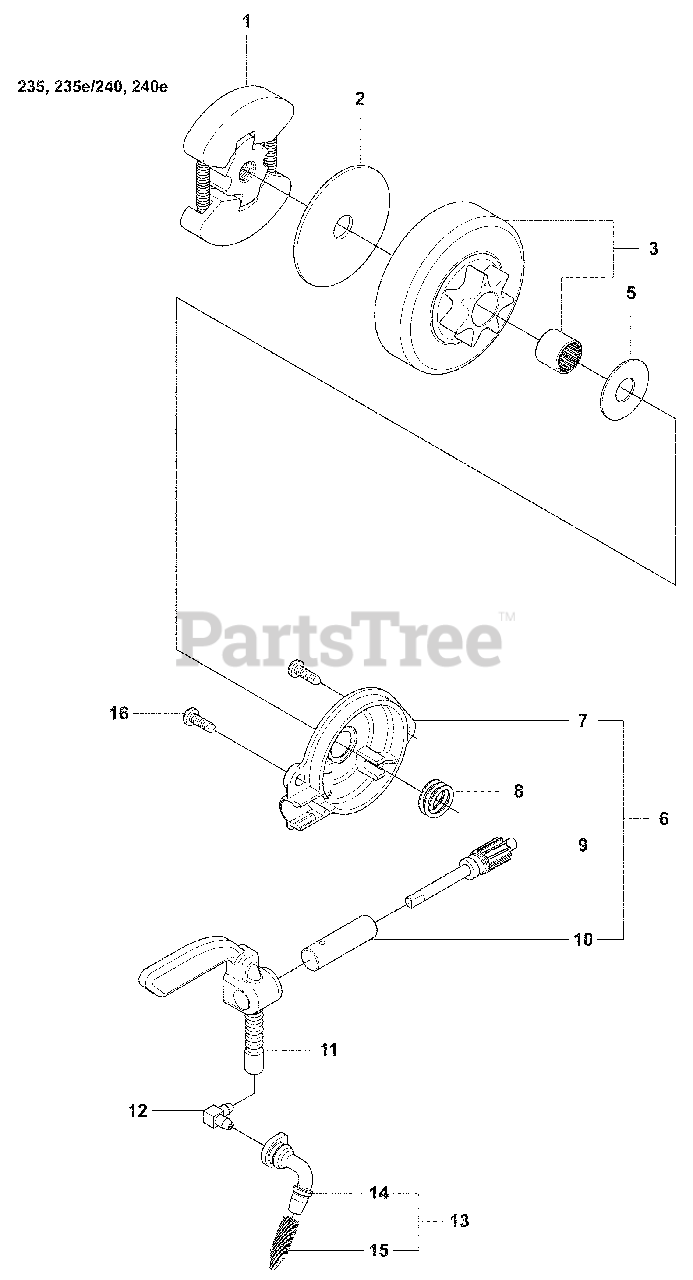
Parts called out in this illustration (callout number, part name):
1	ASSY- CLUTCH
2	WASHER, CLUTCH (LARGE)
3	3/8-6 TOOTH DRUM ASEMBLY
3	.325-7 TOOTH DRUM ASEMBLY
5	WASHER, THRUST
6	ASSEMBLY OIL PUMP
7	HOUSING, PUMP
8	GEAR- WORM
9	PLUNGER & GEAR
10	BARREL, PUMP
11	OIL BLOCK
12	ELBOW FITTING
13	PICK UP ASSEMBLY OIL TANK
14	PICK-UP SEAL
15	SPRING, FILTER
16	SCP#6-19 X .437 .PL. PAN.
